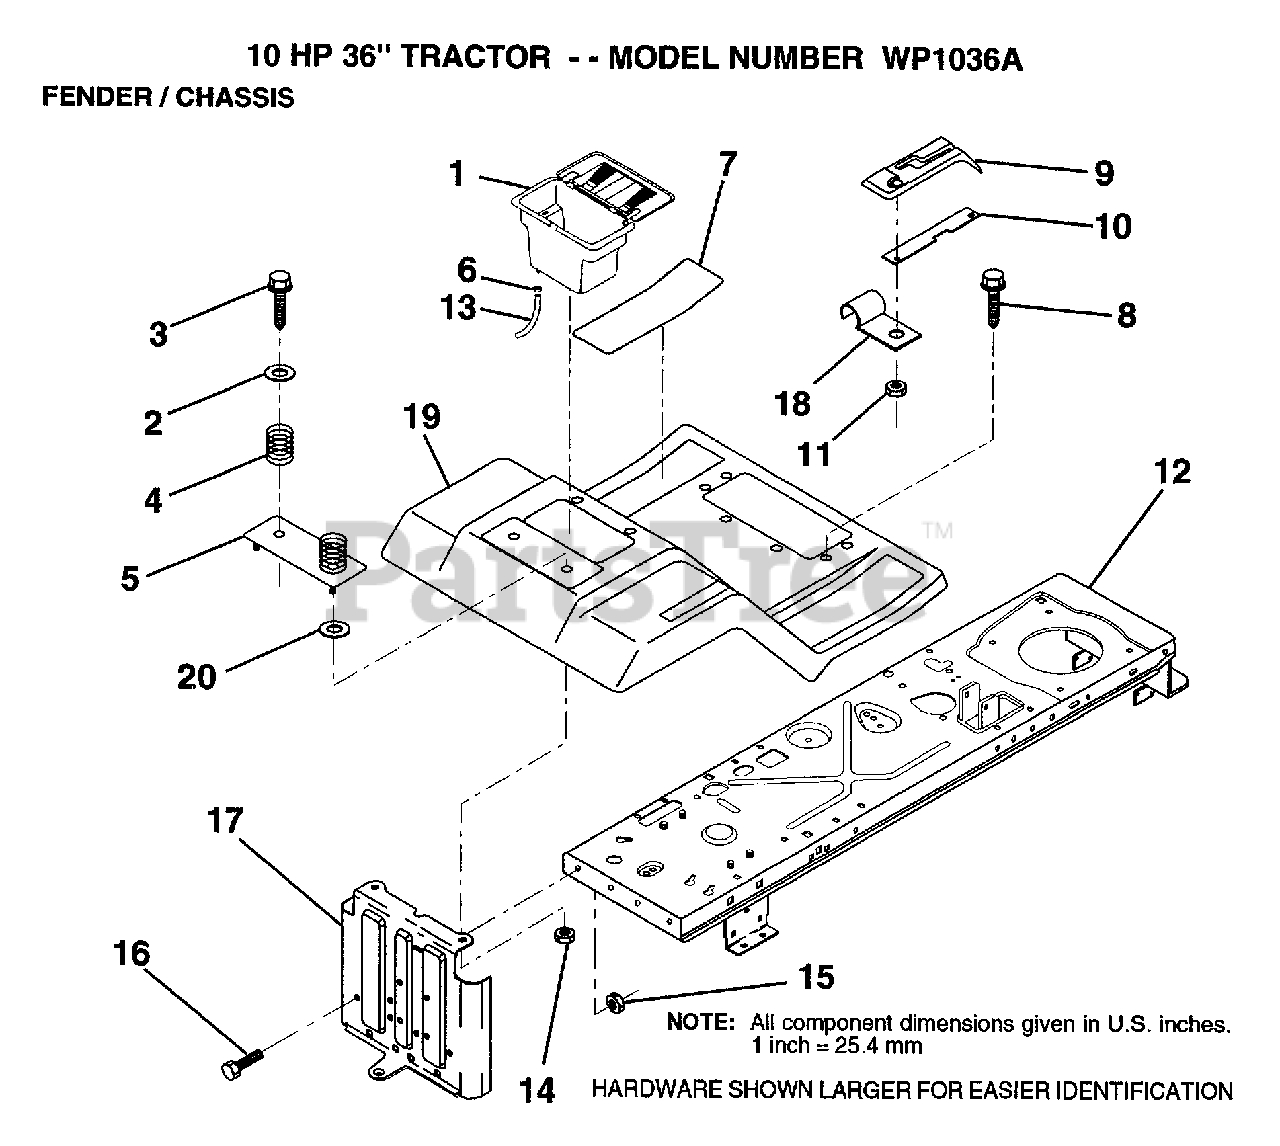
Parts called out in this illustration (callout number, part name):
2	WASHER
3	SCREW
4	SPRING COMPRESSIO
5	BTRY FENDER PLATE
6	HOSE CLAMP T
7	PAD FOOTREST
8	SCREW
9	CONSOLE SHFT 4SP
11	NUT
14	NUT
16	BOLT
17	DRAWBAR
18	"CLIP,INSULATOR"
